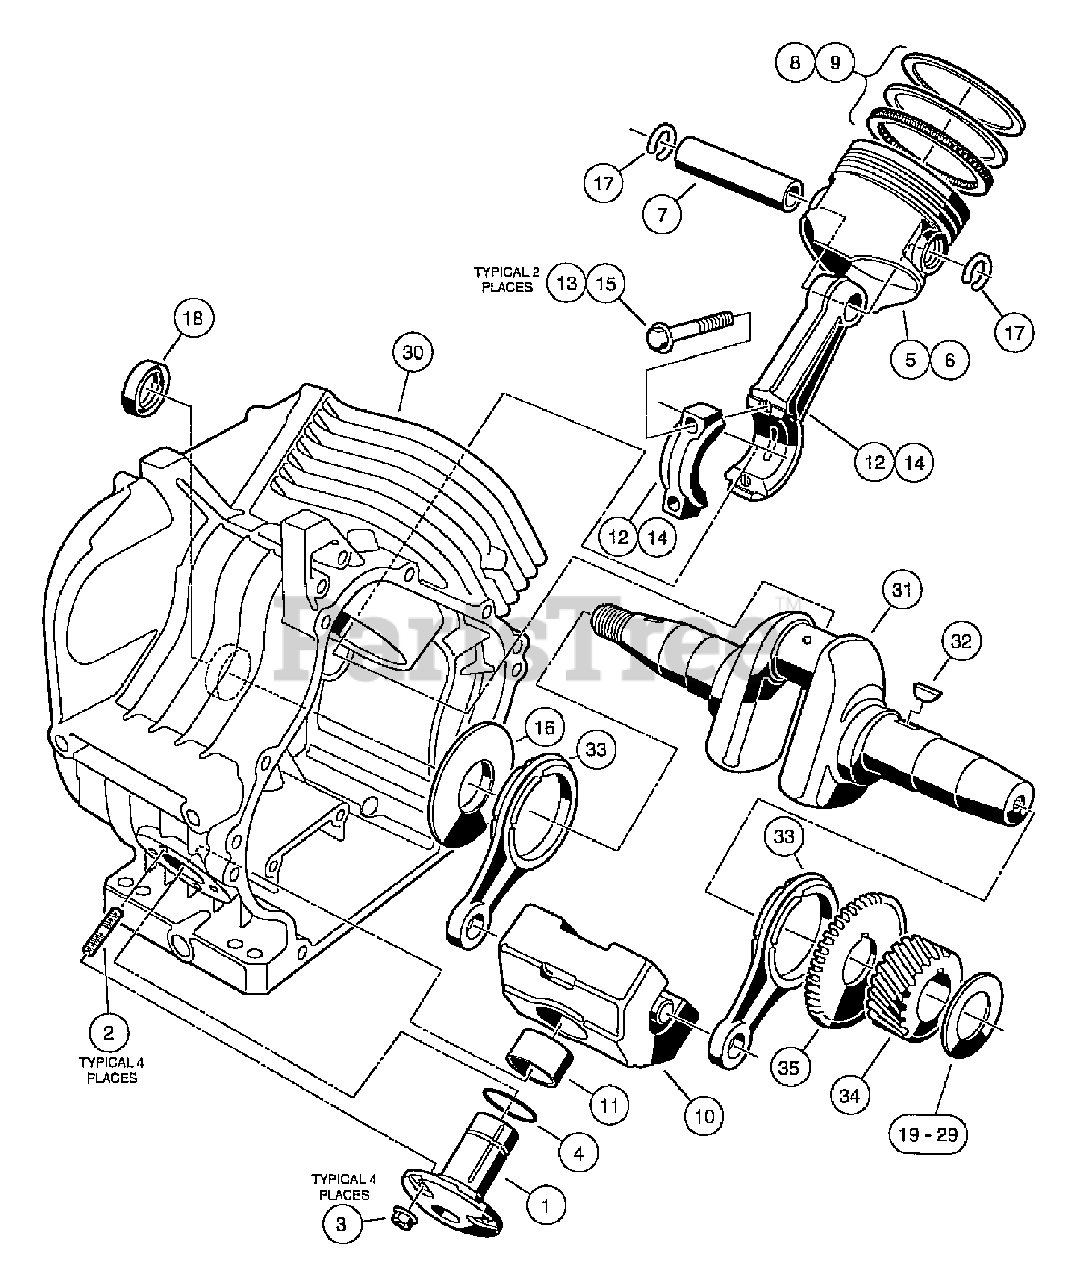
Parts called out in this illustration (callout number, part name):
1	Shaft, Guide, Counterbalance
2	Stud, 6x14
5	Piston, Standard
6	Piston, 0.50 mm Oversize
7	Pin, Piston
8	Ring Set, Standard Piston
9	Ring Set, Piston, 0.50 mm Oversize
10	Weight
11	Bearing, Plain
12	Rod Assy Connecting Rod Sid
13	Bolt
14	Rod Assembly Connnecting Rod 0.5mm
15	Bolt
19-29	Shim, Crankshaft, 1.18mm
19-29	Shim, Crankshaft, 1.25mm
19-29	Shim, Crankshaft, 1.32mm
19-29	Shim, Crankshaft, 1.39mm
19-29	Shim, Crankshaft, 1.46mm
19-29	Shim, Crankshaft, 1.53mm
19-29	Shim, Crankshaft, 1.60mm
19-29	Shim, Crankshaft, 1.67mm
19-29	Shim, Crankshaft, 1.74mm
19-29	Shim, Crankshaft, 1.11mm
19-29	Shim, Crankshaft, 1.81mm
30	Crankcase Complete, FE350 (cw)
31	Crankshaft, FE350 Left-Hand, 22-Tooth
34	Gear, Helical
35	Gear, Spur
